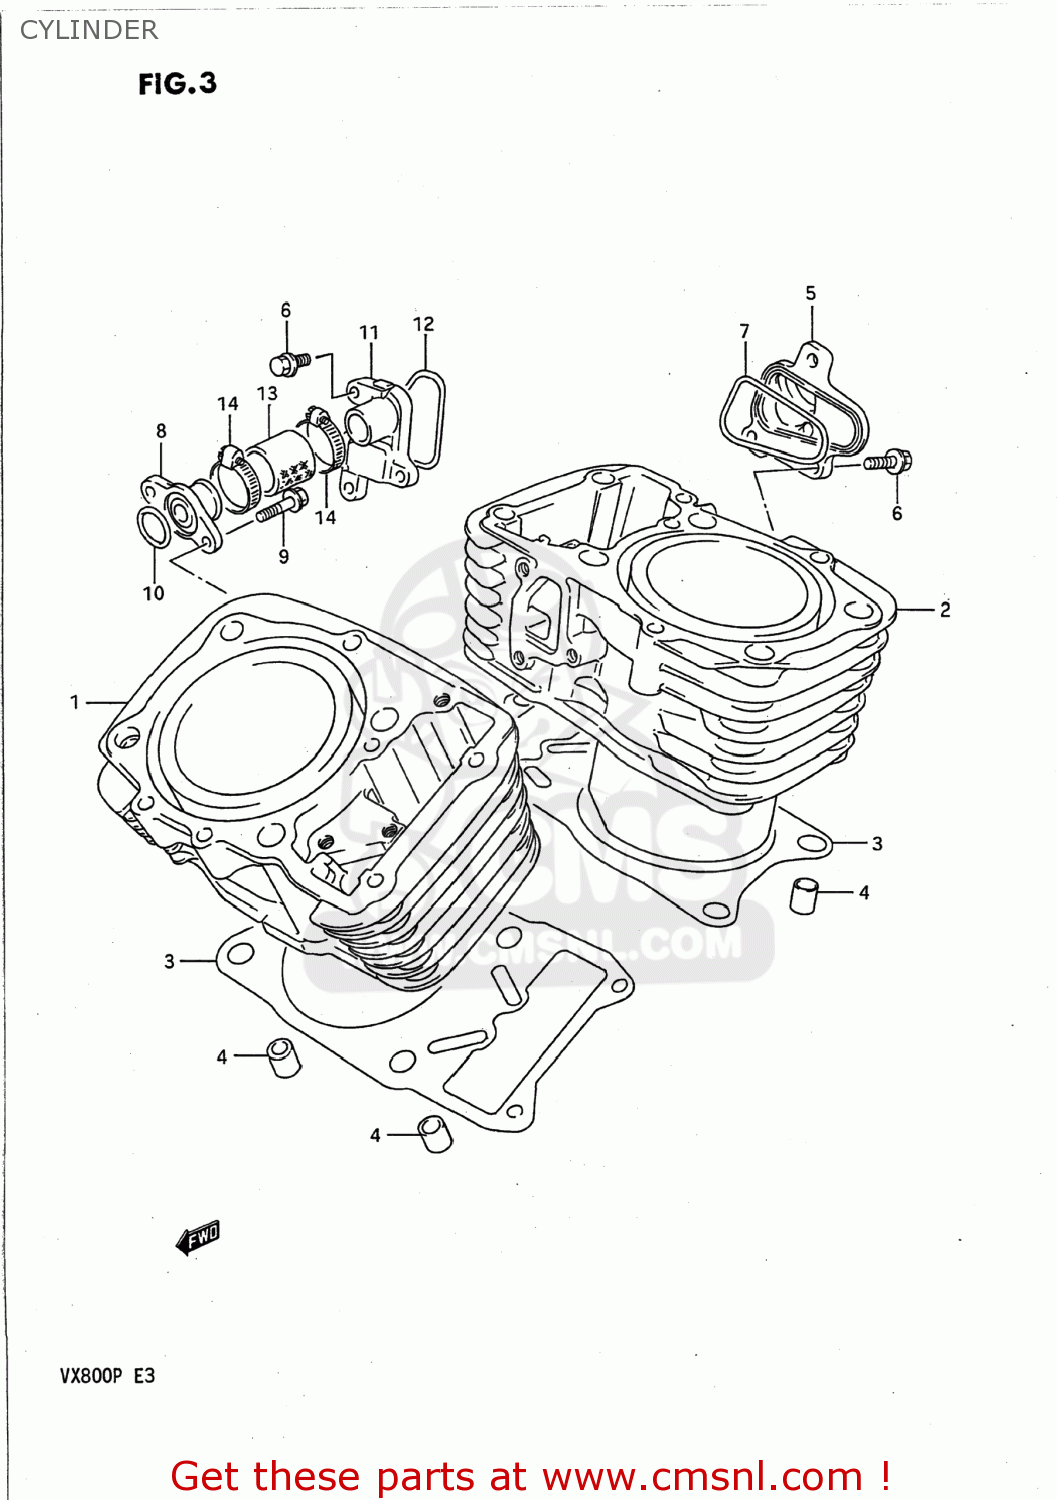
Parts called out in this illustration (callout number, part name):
1	CYLINDER,FRONT
2	CYLINDER,REAR
3	GASKET,CYLINDER (NAS)
4	PIN
5	CHAMBER,WATER,INLET
6	BOLT
7	O RING,INLET WATER CHAMBER
8	UNION,WATER INLET
9	BOLT
10	O RING(D:2.4,ID:15.8)
11	CHAMBER,WATER,OUTLET
12	O RING,OUTLET WATER CHAMBER
13	HOSE,RADIATOR
14	CLAMP
